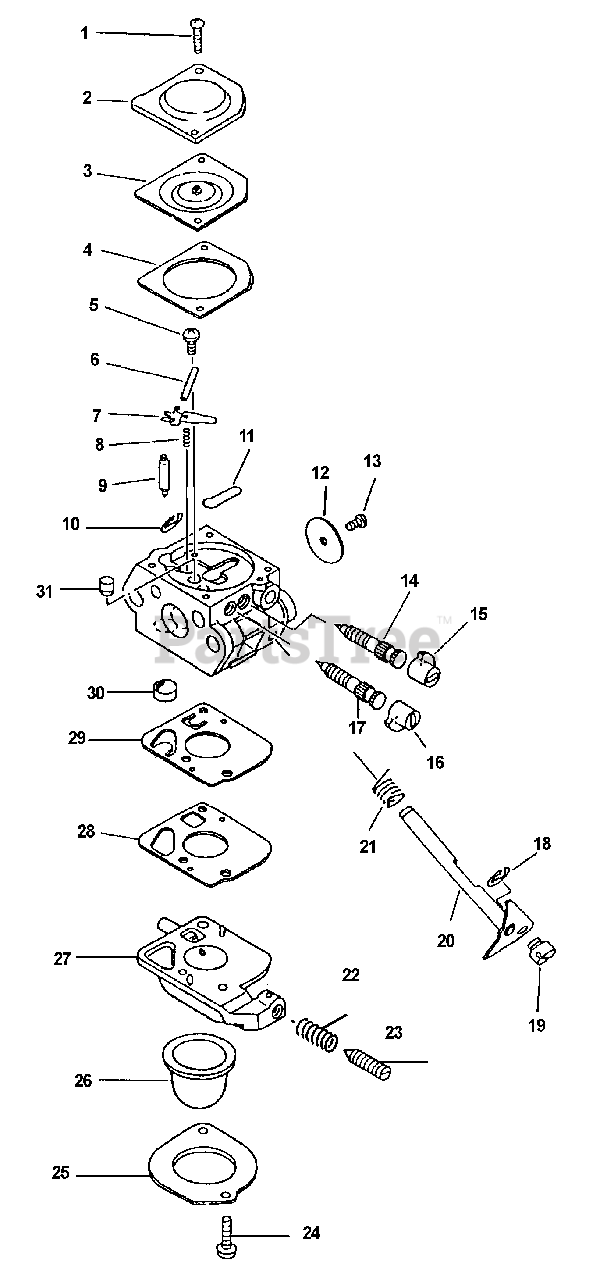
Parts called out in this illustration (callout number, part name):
2	COVER, METERING DIAPHRAGM
3	DIAPHRAGM, METERING
4	GASKET, METERING DIAPHRAGM
6	PIN, METERING LEVER
7	LEVER, METERING
11	PLUG, WELCH
12	VALVE, THROTTLE
14	NEEDLE, LOW SPEED
15	CAP, LIMITER - WHITE
16	CAP, LIMITER - RED
17	NEEDLE, HIGH SPEED
20	SHAFT, THROTTLE
21	SPRING, THROTTLE RETURN
22	PIECE, FRICTION
23	SCREW, IDLE ADJUST
25	RETAINER
26	BULB, PURGE
27	BODY ASSY, PURGE
28	GASKET, FUEL PUMP
29	DIAPHRAGM, FUEL PUMP
30	STRAINER
31	NOZZLE, CHECK VALVE
